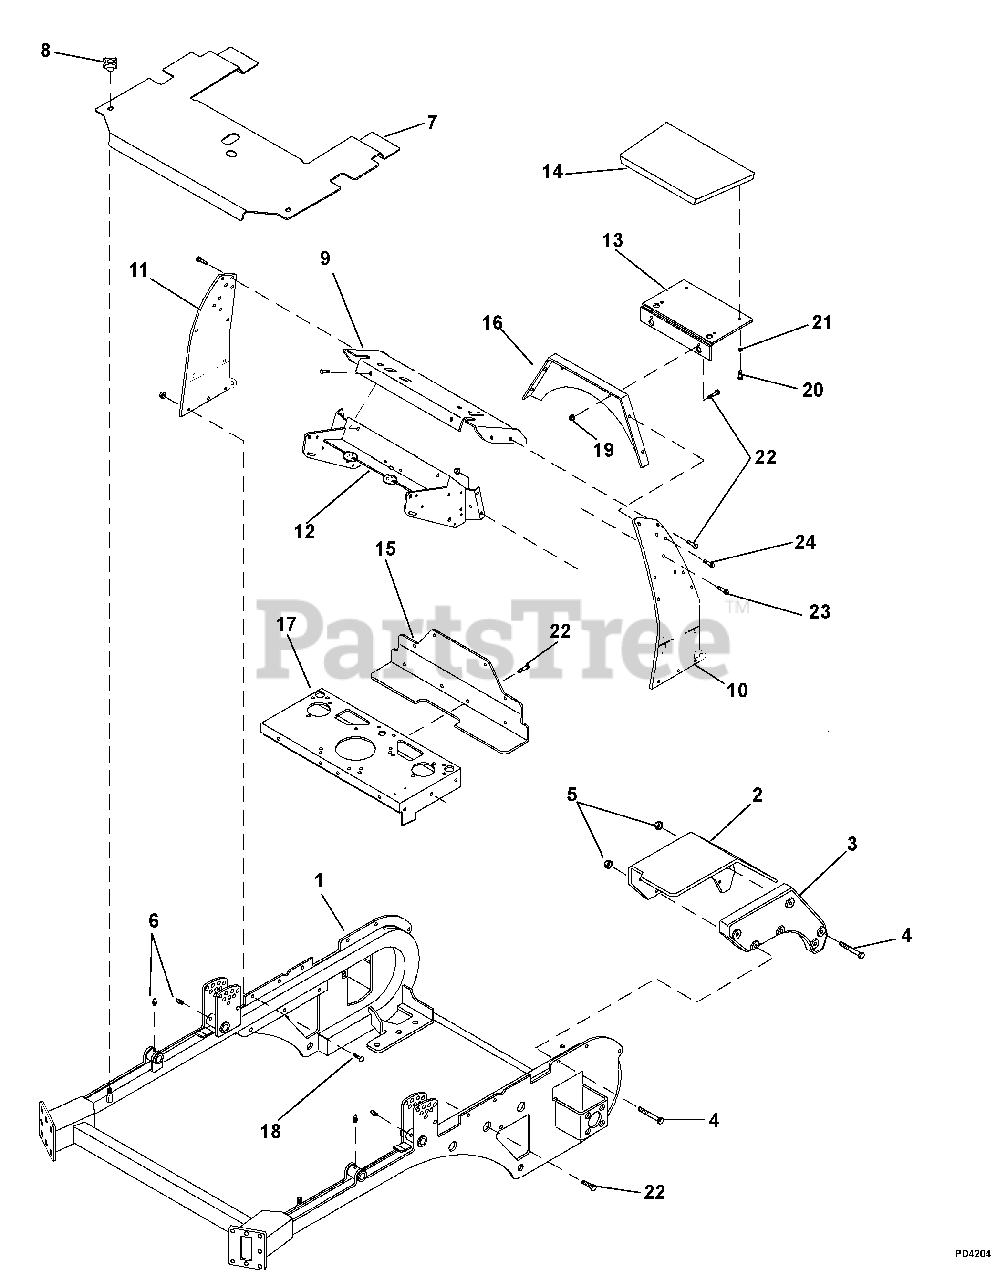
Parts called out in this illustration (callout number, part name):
2	Fender, Left
4	Screw, Hex, Flat M8 x 1.25 x 70 10.9
5	Nut, Locking, Flange M8-1.25
6	Zerk, Grease, Fitting, 1/4-28 Strgt
7	Assy, 48 Shield w/Decals (994109)
8	Knob, 3/8-16 Insert
9	Console, ProStance w/Decals Flat
10	Weldment, Left Hand Side Support
11	Weldment, Right Hand Side Support
12	Weldment, Float Console
13	Plate, Thigh Pad
14	Thigh Pad, Black
16	Weldment, Thigh Plate
17	Engine Deck w/Decals Gravely
18	Carriage Bolt, M10 x 1.5 x 25
19	Nut, Flat, Nyloc M10 x 1.50 GR10
20	Bolt, Hex, .25-20 x .75
21	Washer, Lock .25 x .062
22	Screw, Hex, Flat M10 x 1.5 x 20 Full Thread
23	Screw, Hex, Flat M10 x 1.5 x 25 Full Thread
24	Screw, Cap Special
